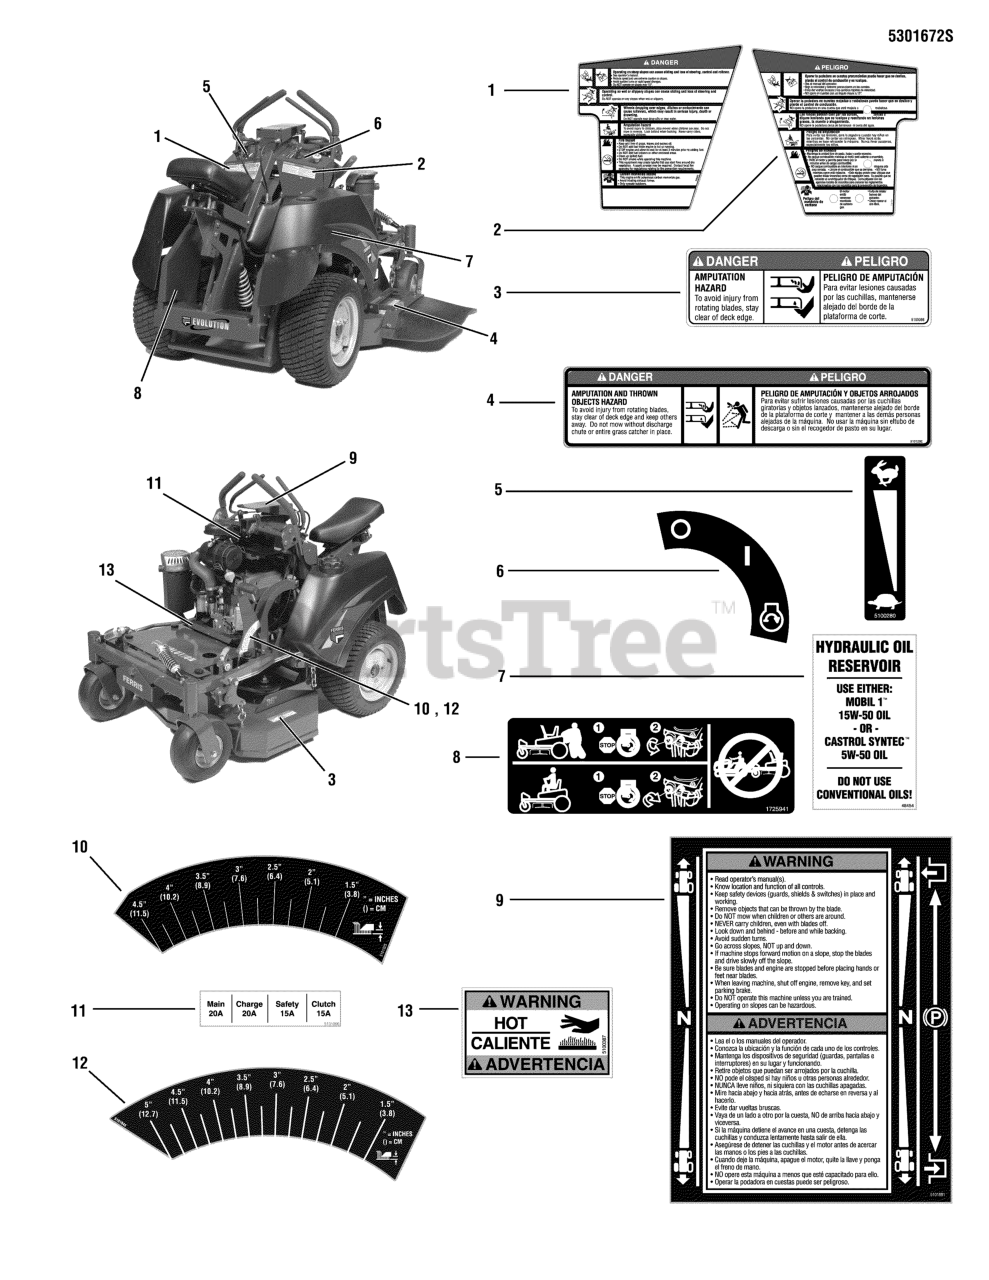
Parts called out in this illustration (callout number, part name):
1	DECAL, MAIN SAFETY, EVOLUTION
2	DECAL, MAIN SAFETY, EVOLUTION (SP)
3	DECAL, DANGER, MOWER
4	DECAL, DANGER, MOWER DISCHARGE,8.75X2.13
5	DECAL, THROTTLE CONTROL
6	DECAL, IGNITION SWITCH
7	DECAL, OIL RESEVOIR
8	DECAL, CZT HYDRO RELEASE
9	DECAL, MOTION CONTROL GUARD, EVOLUTION
10	DECAL, DECK HEIGHT, EVOLUTION, 36"
11	DECAL, FUSE LOCATION
12	DECAL, DECK HEIGHT, EVOLUTION, 48"
13	DECAL, WARNING, HOT
